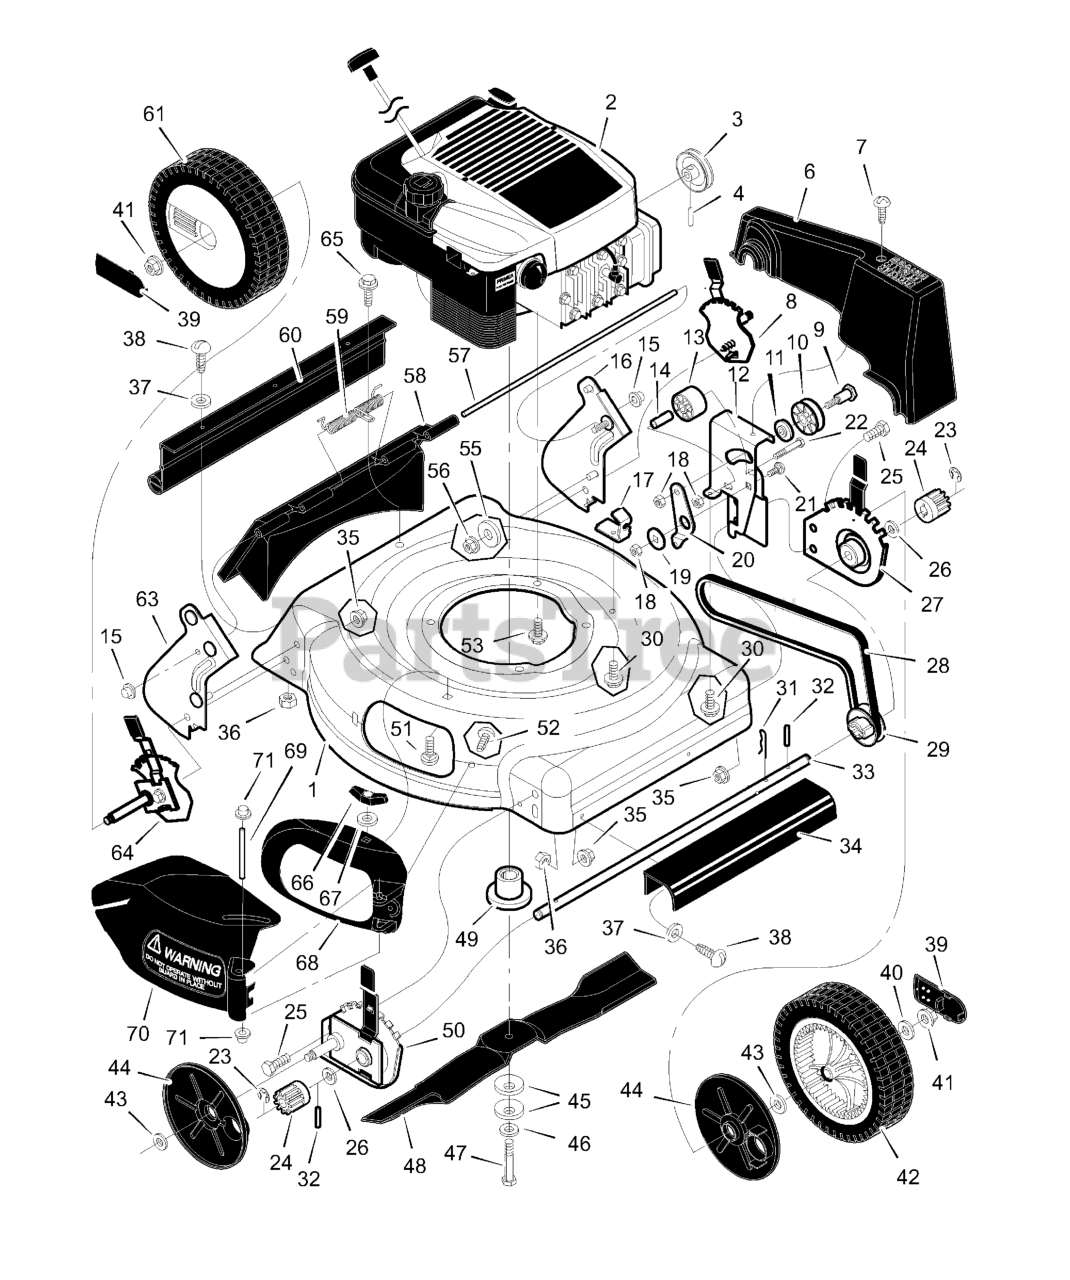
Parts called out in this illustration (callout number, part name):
1	Housing
2	Engine *
3	Pulley, Engine
4	Pin, Spring
6	Cover, Belt (Black)
8	Adjuster, Left Height
9	Bolt, Shoulder
12	Bracket, Idler Support
13	Pulley, Idler
14	Bearing
15	Nut, Push
16	Bracket, Left Handle
17	Bracket, Cable
18	Nut, Hex
20	Arm, Idler
21	Bolt, Carriage
22	Bolt, Shoulder
24	Gear, Pinion
25	Bolt
27	Adjuster, Left Frt. Height
29	Pulley, Axle
31	Pin, Hair
32	Pin, Spring
34	Cover, Axle (Black)
35	Nut, Flange
36	Nut, Hex
39	Cap, Hub
40	Washer
41	Nut, Flange
42	Wheel, Drive
44	Cover, Dust
45	Washer, Belleville
49	Adapter, Blade
50	Adjuster, Right Frt. Height
51	Bolt, Carriage
53	Bolt, Engine
55	Washer
56	Nut, Flange
57	Rod, Pivot
58	Door, Rear (Black)
60	Deflector, Rear
61	Wheel, Rear
63	Bracket, Right Handle
64	Adjuster, Right Height
66	Wingnut
67	Retainer, Push
68	Bezel (Black)
69	Pin, Pivot
70	Deflector, Chute (Black)
71	Push On Cap
